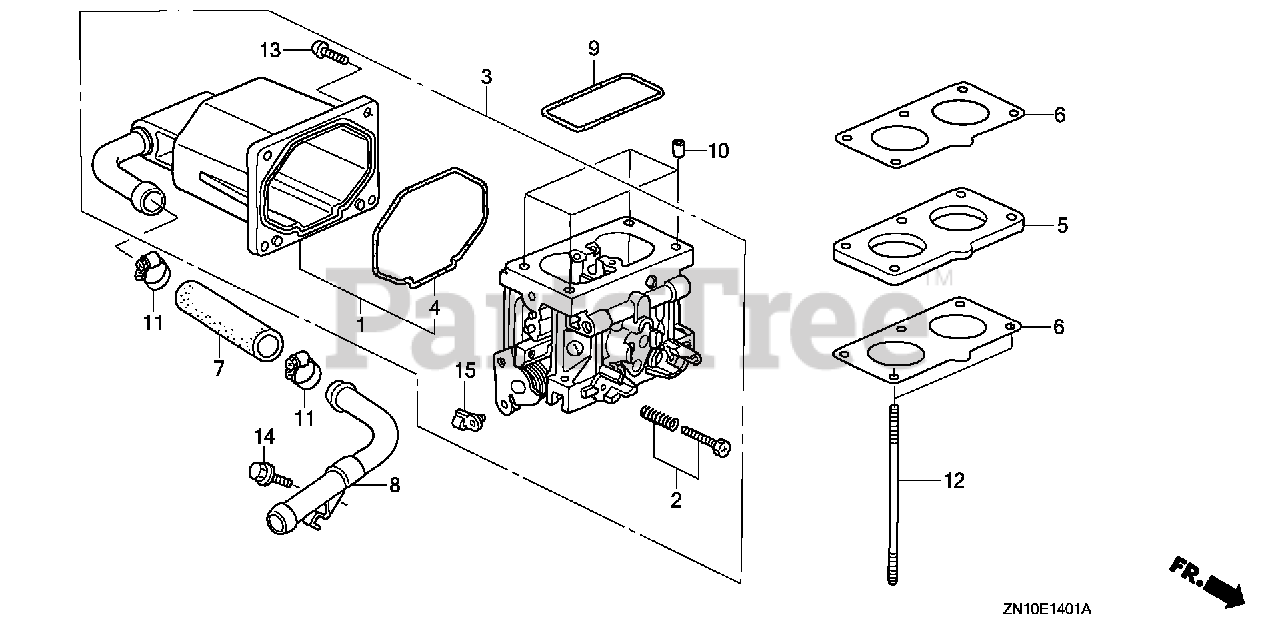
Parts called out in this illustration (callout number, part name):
1	CHAMBER SET, FLOAT
2	SCREW SET, THROTTLE (ADVENTURE GREEN) (CARBURETOR NO.)
3	CARBURETOR ASSY. (BKL1A A)
4	GASKET, FLOAT CHAMBER
5	INSULATOR, CARBURETOR
6	GASKET, CARBURETOR
7	HOSE, FUEL
8	JOINT, FUEL
9	GASKET, AIR CLEANER
10	COLLAR A, AIR CLEANER
11	CLAMP A, WATER HOSE
11	CLAMP, WATER HOSE
12	BOLT, STUD (6X108)
13	SCREW, PAN (4X14)
14	BOLT, FLANGE (8X20) Use up to Engine SN 1609606.
15	ARM, THROTTLE LINKAGE (CARBURETOR NO.)
